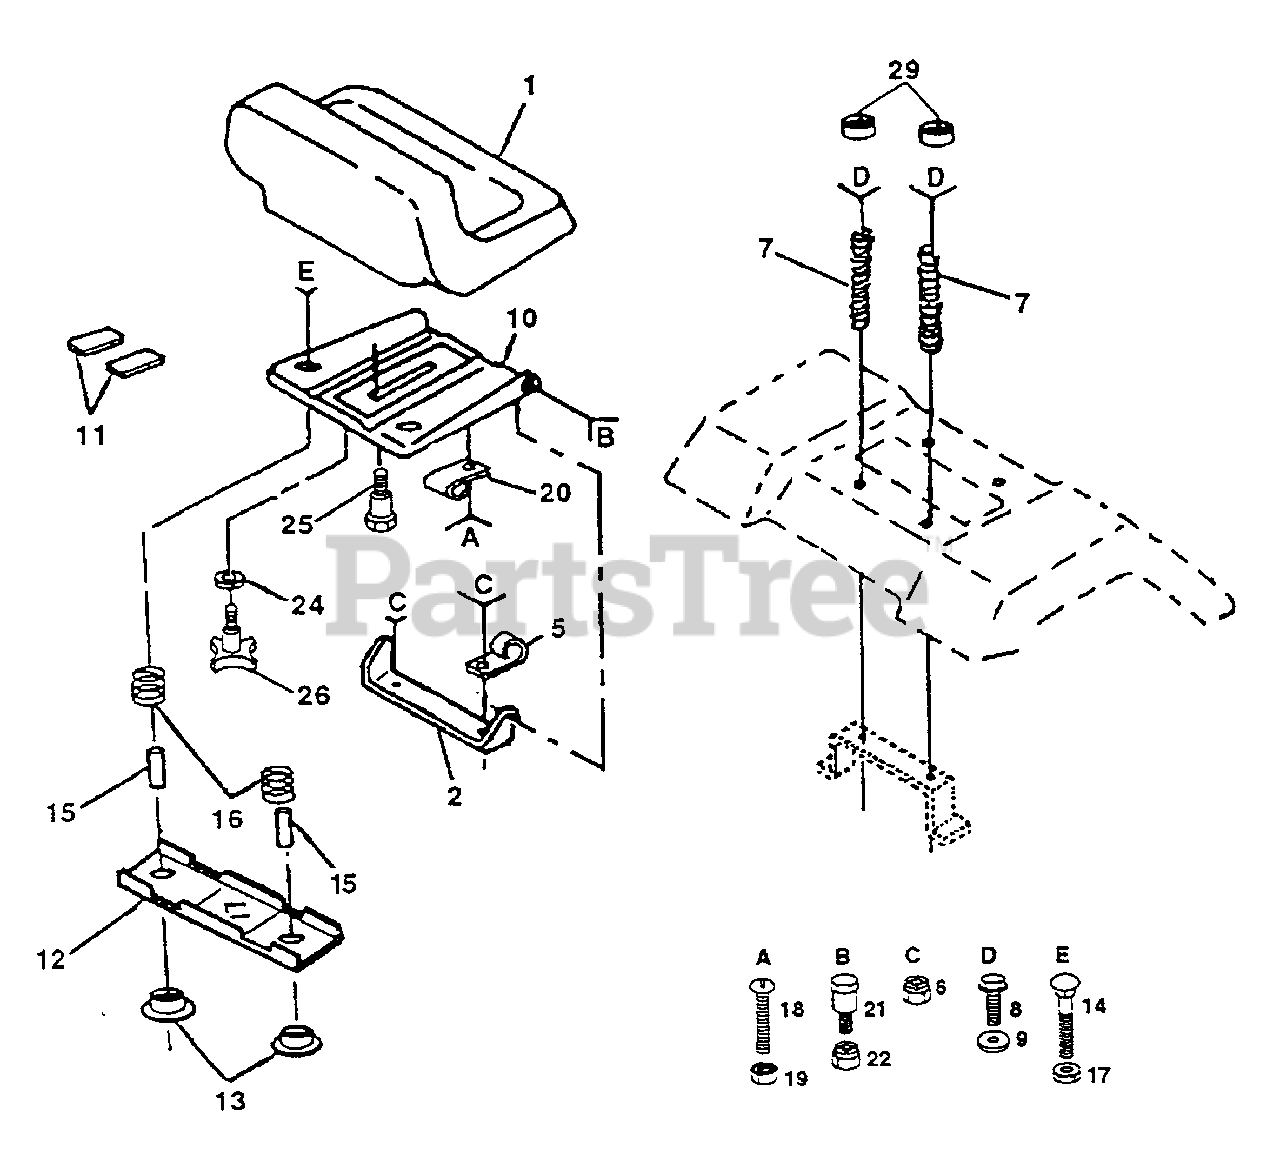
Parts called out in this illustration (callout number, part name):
1	Seat V-560 BLK/blk Std
2	Bracket Pivot Seat 8 720
5	Clip Line Fuel 13/32 Mtg Hole
6	Nut Crownlock 3/8-16 Unc
7	Spring Seat Cprsn 2 250 Blk Zi
8	Screw Hwsh Thdrol 5/16-18 x 1/2
9	Washer 13/32 X 1 X 14 Ga
10	Pan Seat
11	Strip Foam Gray Or Black
12	Bracket Mounting Switch
13	Bushing Snap Blk Nyl 50 Id
14	Bolt Rdhd Sht Nk 1/4-20x1-3/8
15	Spacer Split 28x 88 Yel Zinc
16	Spring Cprsn 1 310 Blk Pnt
17	Nut Lock 1/4 Lge Flg Gr 5 Zinc
18	Screw SLTD Pan Hd #10-32 X 1/2
19	Nut Keps #10-32 Unf
20	Clip Insulated 11/32 Mtg Hole
21	Bolt Shoulder 5/16-18 Unc Blkz
22	Nut Crown Lock 5/16-18
24	Washer 17/32 X 1-3/16 X 12 Ga
25	Bolt Shoulder 5/16-18 X 62
26	Knob Seat 1/2-13unc Blk
29	Cap Spring Seat
